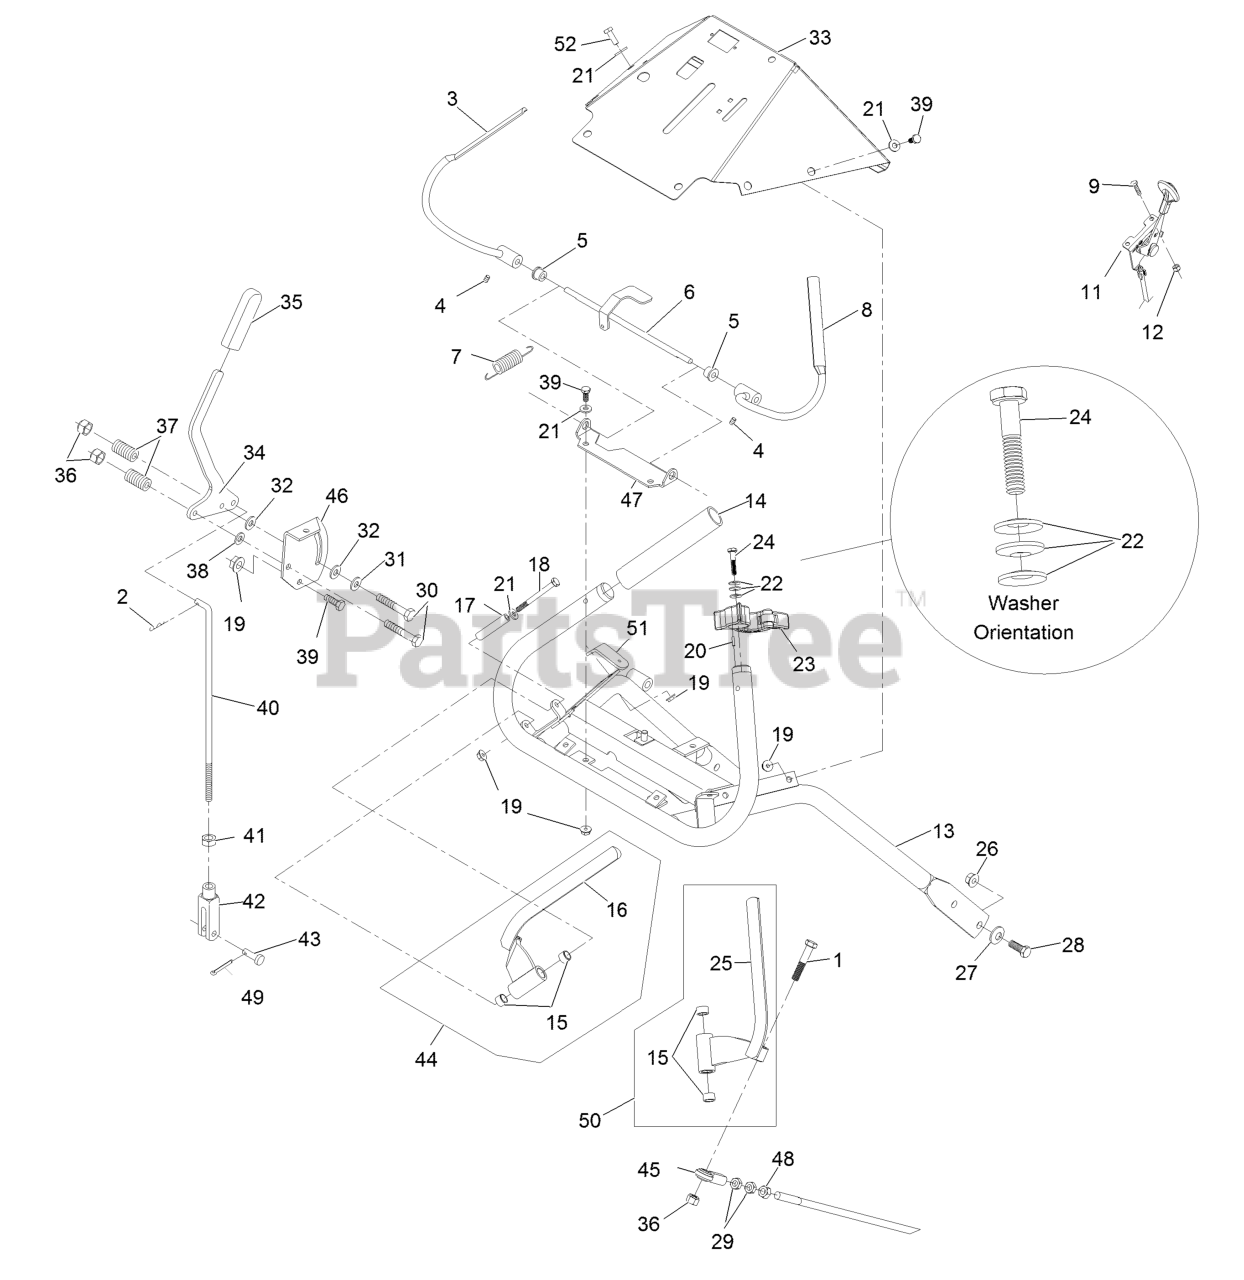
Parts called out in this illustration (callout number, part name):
1	SCREW-HH
2	PIN-COTTER
3	WLD,LH OPC LEVER
4	SCREW-SET
5	BUSHING-NYLON
6	WLD,OPC LEVER AXLE
7	SPRING-EXTENSION
8	WLD,RH OPC LEVER
9	BOLT-CARR
11	CONTROL-THROTTLE
12	NUT-LOCK, NI
13	WLD,TTH ECS HANDLE
14	GRIP-BAR, HANDLE
15	BUSHING-SLEEVE
16	WLD,LH DRIVE LEVER
17	BUSHING-LEVER, DRIVE
18	SCREW-HH
21	WASHER-FLAT
22	WASHER-SPRING
23	ASM,LATCH RH THUMB
24	SCREW-HH
25	WLD,RH DRIVE LEVER
26	NUT-HHF, WHIZ
27	WASHER-BELLEVILLE
28	SCREW-HH
29	NUT-HJ
30	SCREW-HH
31	WASHER-FRICTION
32	WASHER-FRICTION
33	ASM, CONSOLE WITH DECALS
34	LEVER, SHIFT W/GRIP
35	GRIP-HANDLE, STEERING
36	NUT-LOCK, NI
37	SPRING-COMPRESSION
38	WASHER-PLAIN
39	SCREW-HH
40	ROD,SPEED CONTROL
41	NUT-JAM
42	YOKE-ADJUSTABLE
43	PIN-CLEVIS
44	DRIVE LEVER-ASM, LH
45	JOINT-BALL, END
46	BRACKET,SHIFTER SLIDE (PL
47	BRACKET,OPC AXLE
48	NUT-HEX
49	PIN-COTTER
50	DRIVE LEVER-ASM, RH
51	BRACKET-RELAY
52	SCREW-HH
